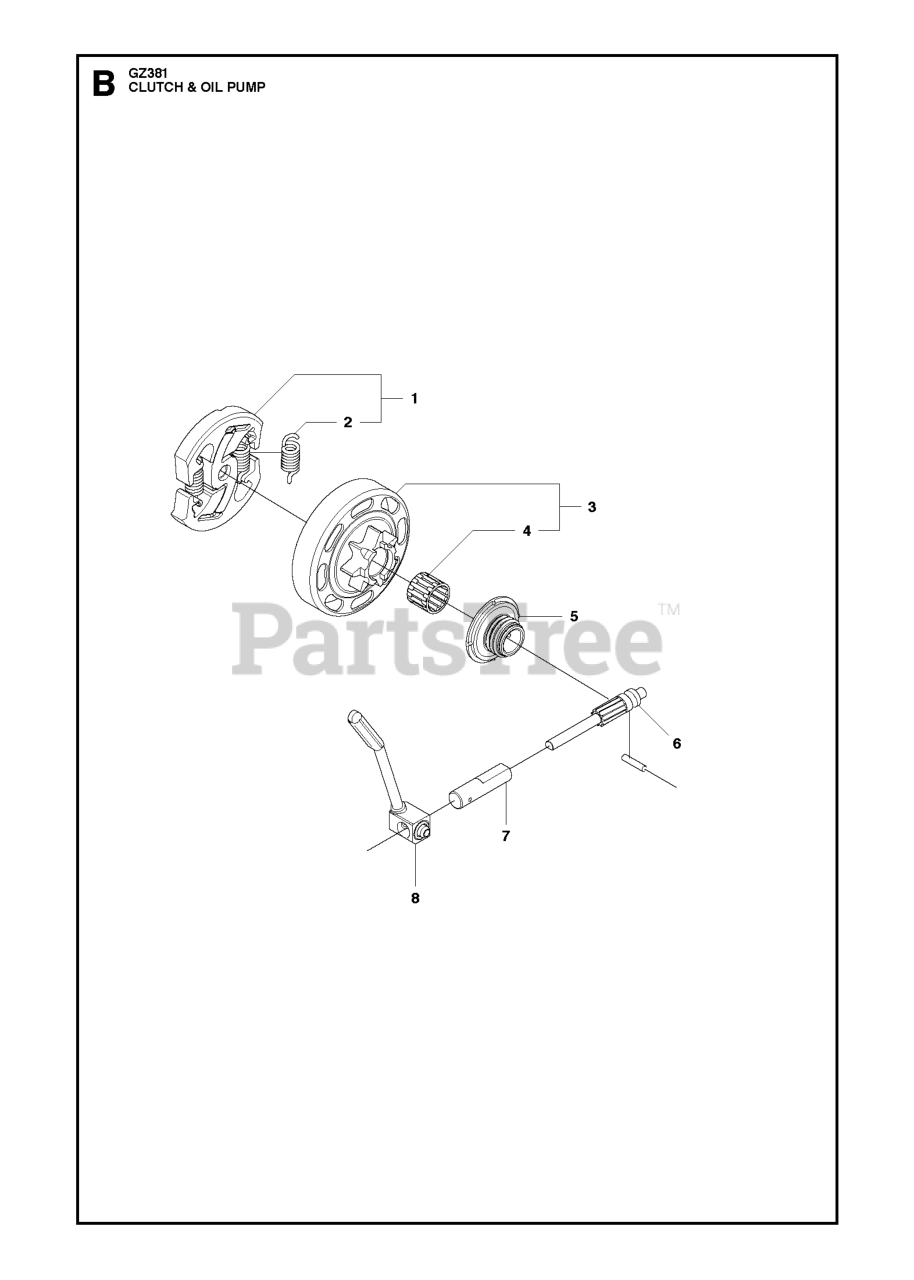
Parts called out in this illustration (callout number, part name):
1	CLUTCH ASSY
2	CLUTCH SPRING
3	CLUTCH DRUM ASSY
4	SUPPORT BUSHING
5	ASSY WORM GEAR
6	PISTON PUMP
7	PUMP CYLINDER
8	OIL HOSE
